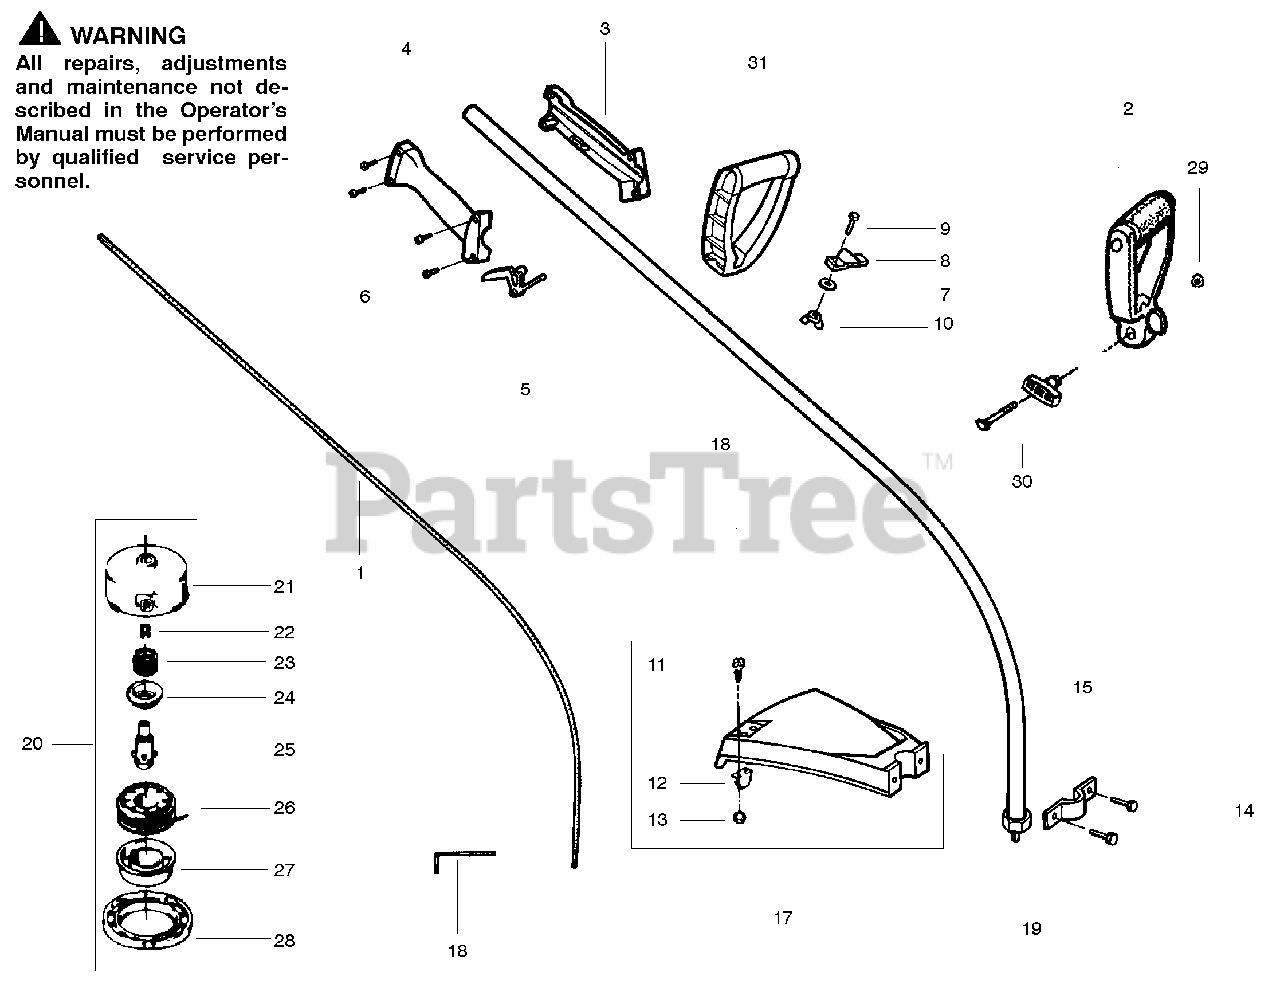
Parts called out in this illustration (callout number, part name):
3	Throttle Hsg. (Left)
4	Throttle Hsg. (Right)
5	Throttle Lever
10	Nut
13	Locknut
15	Bracket Shield
16	Hex Wrench (5/32)
17	Shield Kit Ass’y.
18	Drive Shaft Hsg.
20	Cutting Head Ass’y.
21	Hub Ass’y.
24	Spring Cap
27	Release Button
30	“T” Handle Ass’y.
31	Handle
31	Carton Contents Bag
31	Operator Manual Type 2
31	Operator Manual Type 3
31	Shaft Warning Decal
31	Instruction Decal
